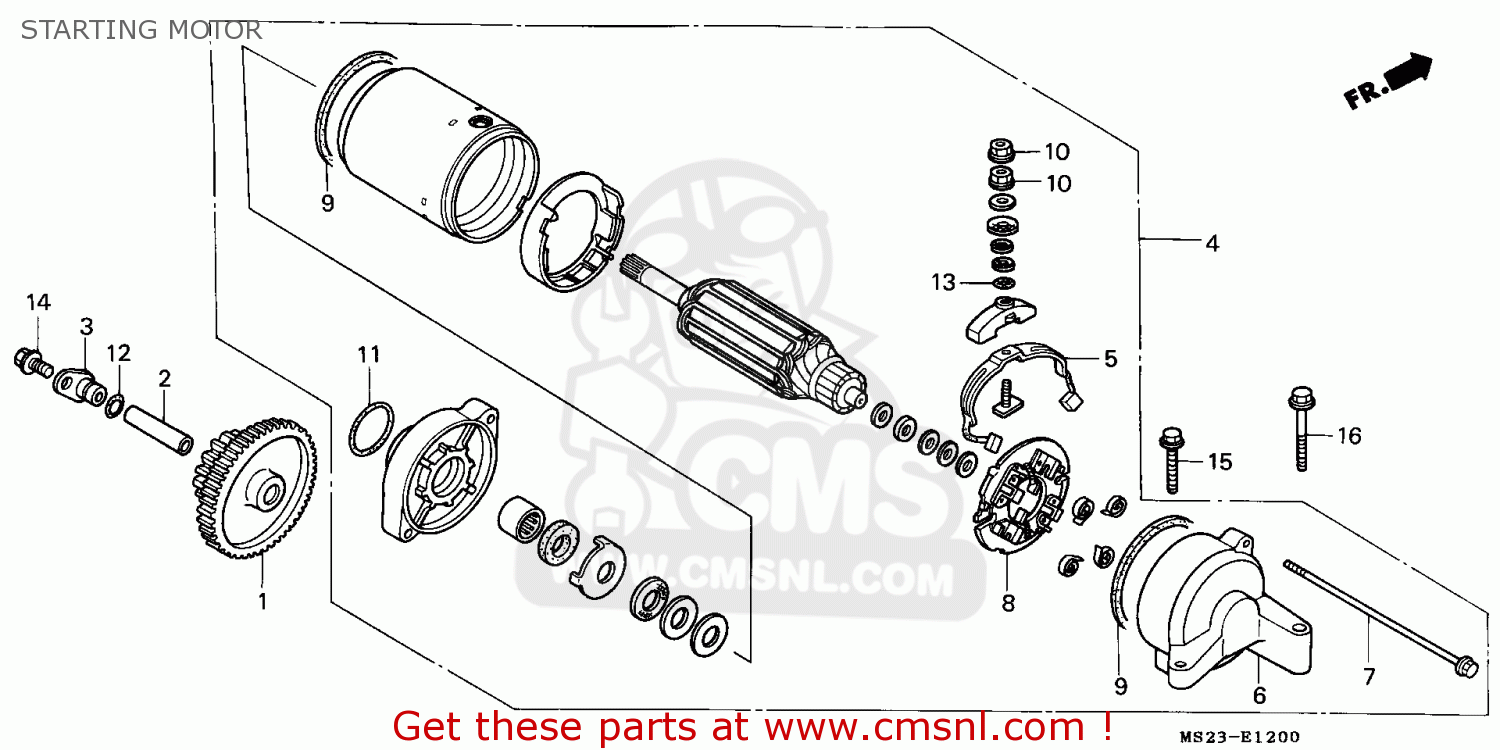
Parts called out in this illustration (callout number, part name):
1	GEAR,STARTER REDU
2	PIN 10X44
3	PLATE,IDLE SHAFT
4	MOTOR ASSY.,START
5	TERMINAL SET
6	BRACKET,RR.
7	BOLT,SETTING
8	HOLDER SET,BRUSH
9	RING
10	NUT-WASHER 6MM
11	O-RING,24.4X3.1
12	O-RING 7X1.7
13	O-RING
14	BOLT,FLANGE 6X14
15	BOLT,FLANGE,6X25
16	BOLT,FLNAGE,6X35
